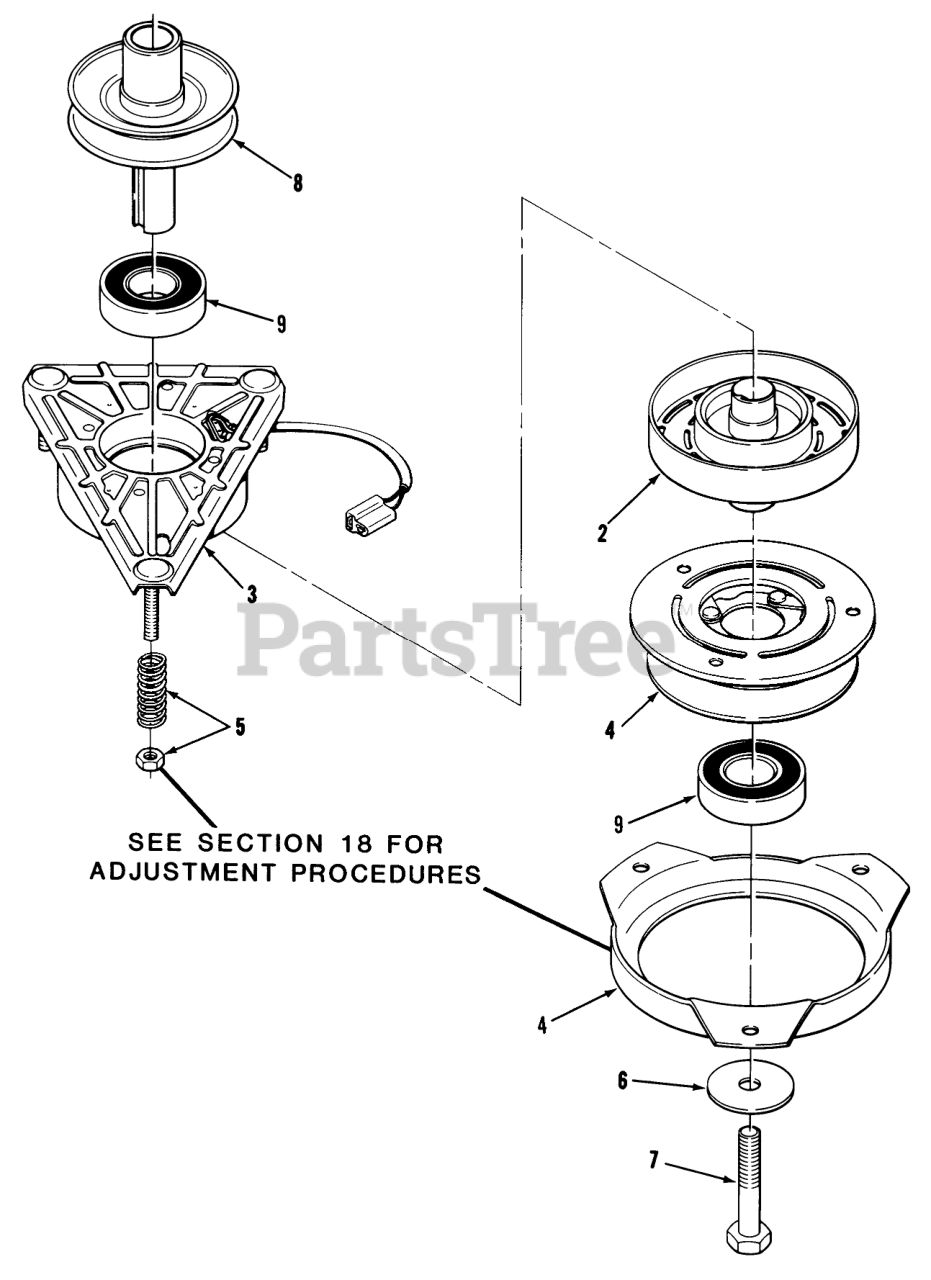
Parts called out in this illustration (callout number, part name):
1	Electric Clutch Assembly (Incl. Ref. #2-5)
2	ASS'Y-ROTOR
3	Field Assembly (Incl. Ref. #9)
4	Armature & Pulley Assy. (Incl. Ref. #9)
5	ACCESS SPRING & NUT
6	WASHER
7	HHCS M10X1.5X120
8	PULLEY-ENGINE
9	BEARING-ELEC CLUTCH
